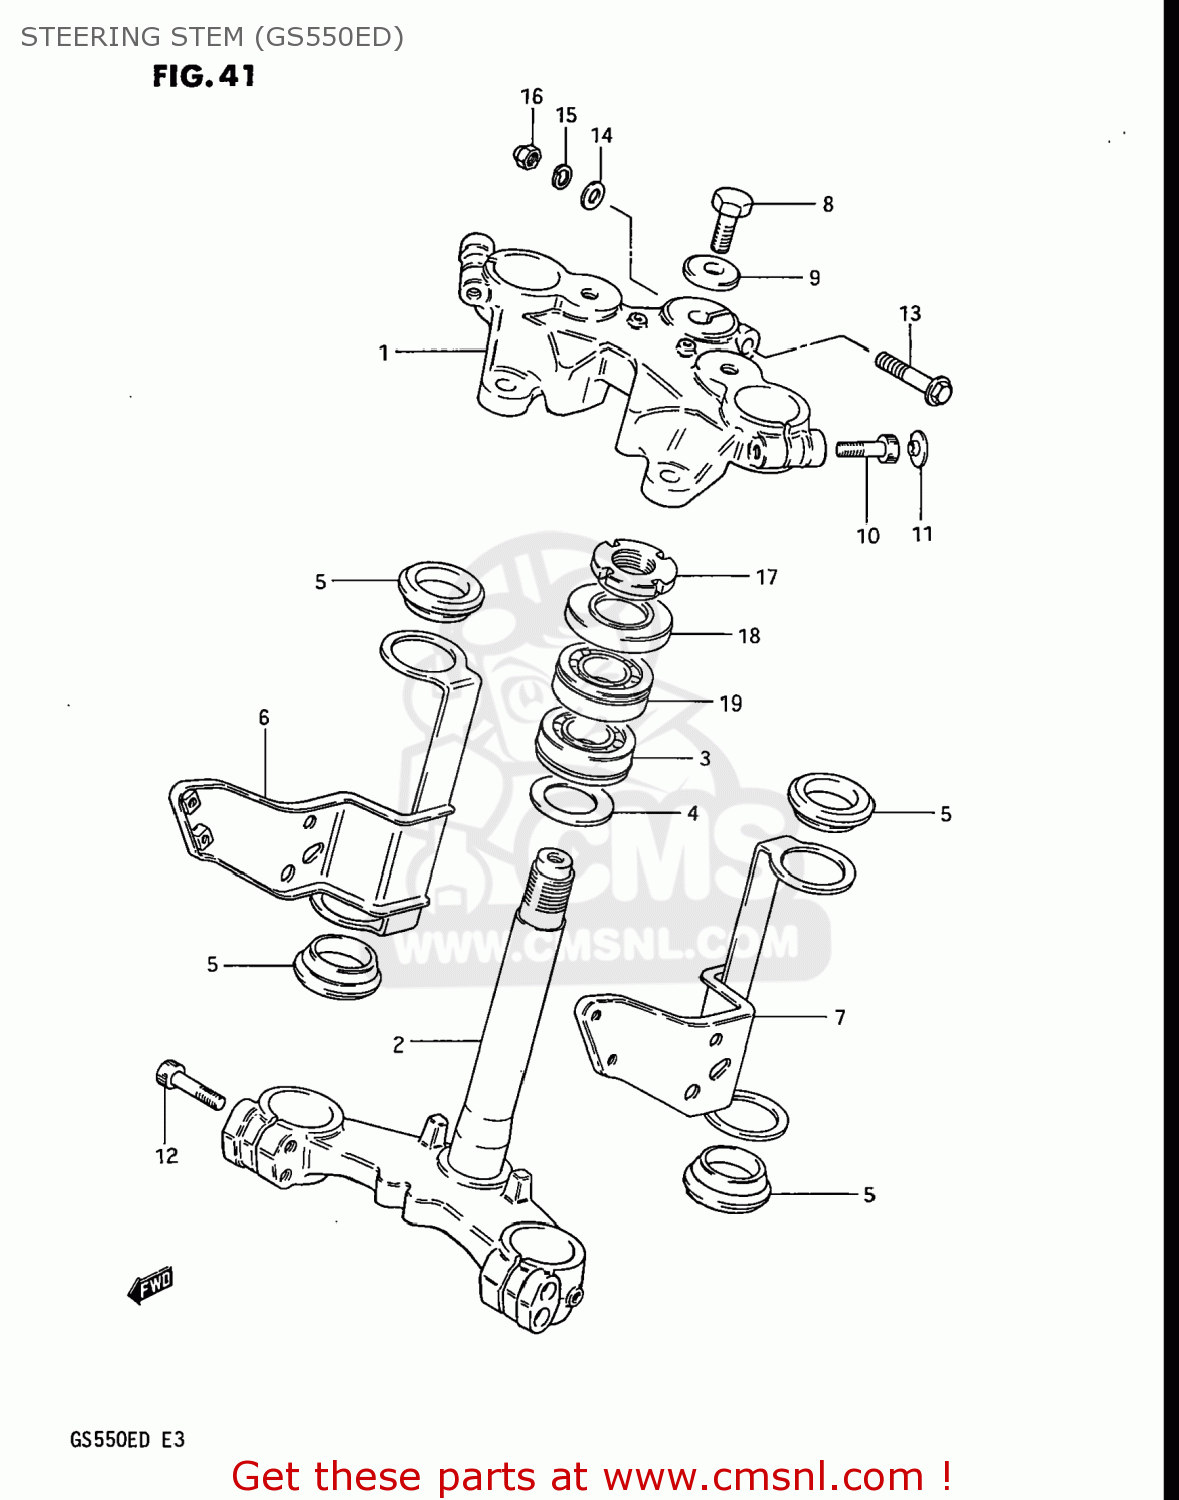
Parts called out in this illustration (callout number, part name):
1	HEAD,STEERING STEM
2	STEM,STEERING
3	BEARING
4	WASHER,THRUST
5	CUSHION,HEADLAMP BRACKET
6	BRACKET,HEADLAMP,RIGHT
7	BRACKET,HEADLAMP,LEFT
8	SUZUKI
9	SUZUKI
10	BOLT
11	CAP(OD:20)
12	BOLT
13	BOLT (8X50)
14	WASHER,8.5X16X
15	LOCK WASHER
16	NUT,M8X1.25X12
17	NUT,STEERING STEM
18	DUST SEAL,STEERING UPR
19	TAPER,ROLLER BEARING
